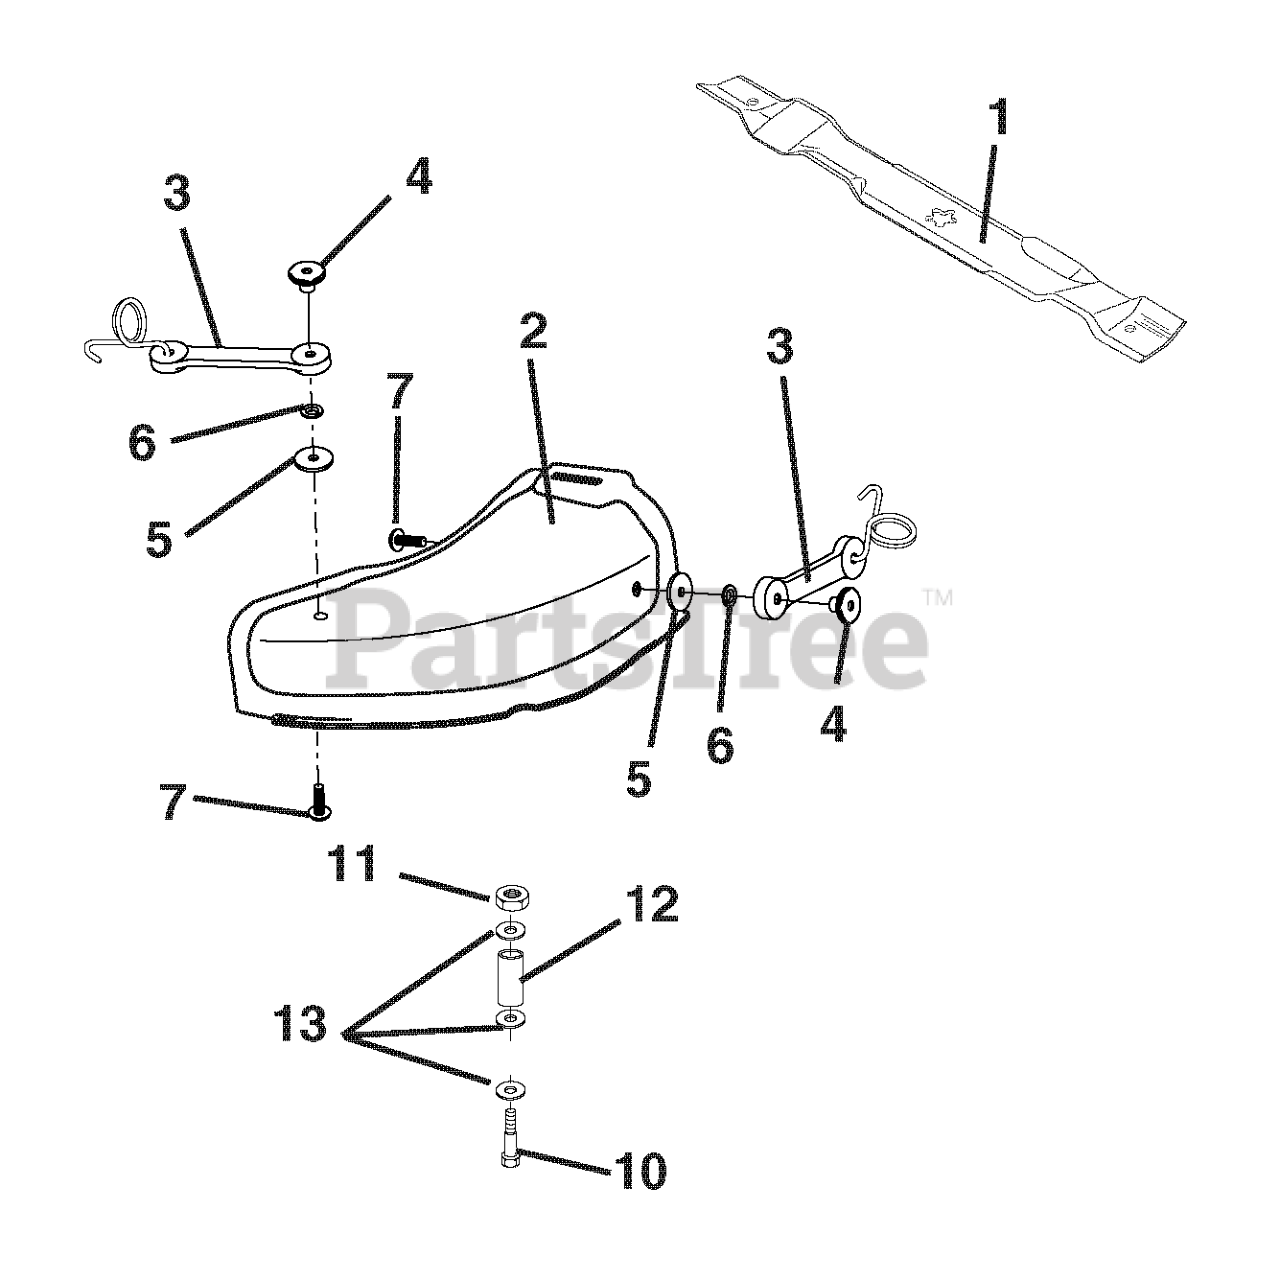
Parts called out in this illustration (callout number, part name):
1	54" MULCH BLADE
2	MULCH COVER 54"
3	LATCH ASSY
4	WELDNUT
6	LOCKWASHER #10
7	SCREW
10	BOLT.HEX.FINISHED.1/4-20
11	LOCKNUT.NYLOC.1/4-20
12	SPACER SPLIT
13	WASHER
